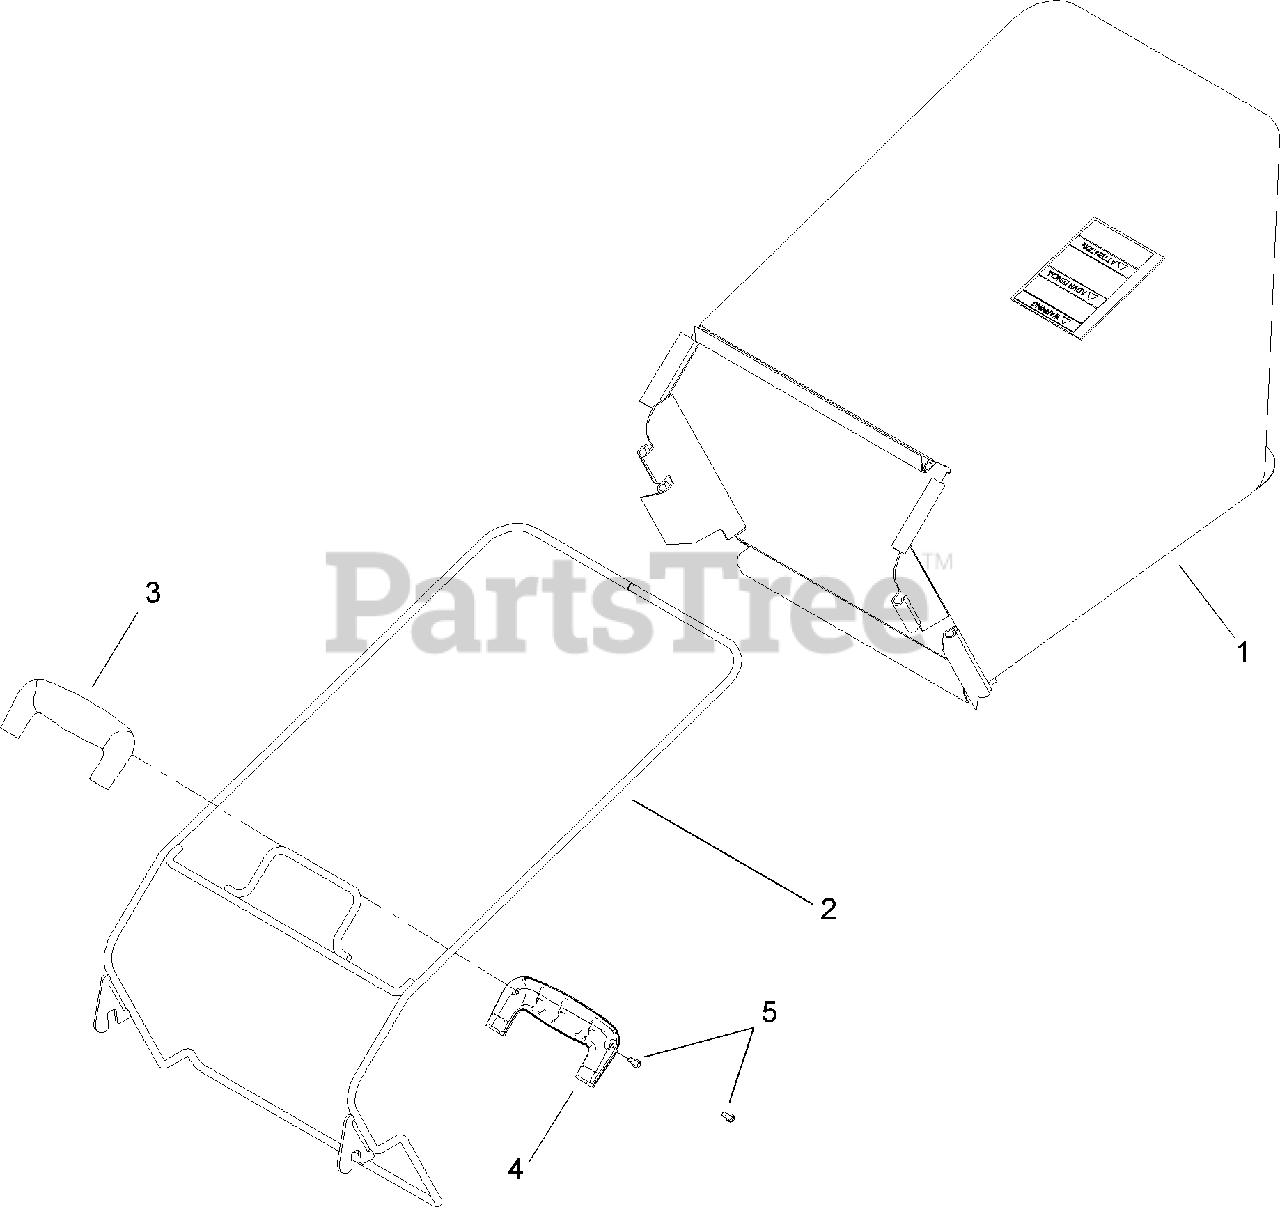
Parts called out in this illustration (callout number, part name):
1	GRASS BAG ASM
2	BRACE-BAG FRAME ASM
3	HANDLE-BAG, TOP
4	HANDLE-BAG, BOTTOM
5	SCREW-PPH
